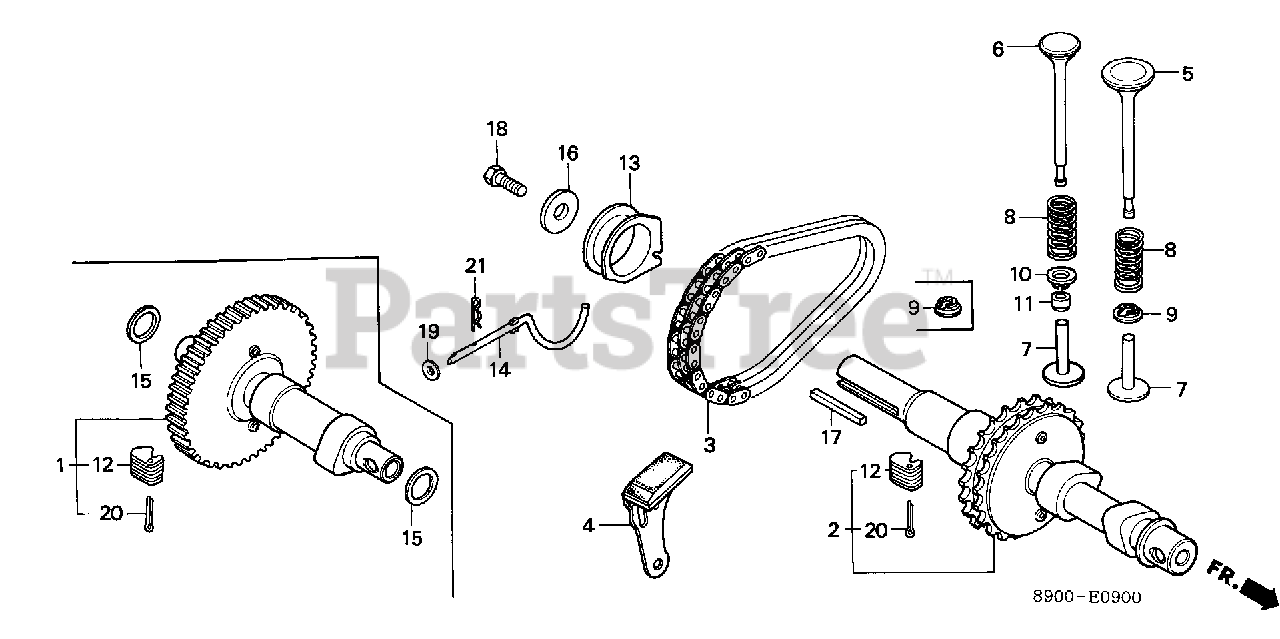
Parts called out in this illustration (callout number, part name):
1	CAMSHAFT ASSY.
1	CAMSHAFT ASSY. (NOT AVAILABLE)
5	VALVE, IN.
6	VALVE, EX.
6	VALVE, EX. (NOT AVAILABLE)
7	LIFTER, VALVE (45.89MM)
7	LIFTER, VALVE (46.04MM)
7	LIFTER, VALVE (46.19MM)
7	LIFTER, VALVE (46.34MM)
8	SPRING, VALVE
9	RETAINER, VALVE SPRING
10	RETAINER, VALVE SPRING
11	ROTATOR, EX. VALVE (NOT AVAILABLE)
12	WEIGHT, GOVERNOR
13	SLIDER, GOVERNOR
14	SHAFT, GOVERNOR ARM
15	WASHER, THRUST (18MM)
19	WASHER, PLAIN (6MM)
20	PIN, SPLIT (3.0X25)
20	PIN, SPLIT (3.0X45)
21	PIN, LOCK (10MM)
